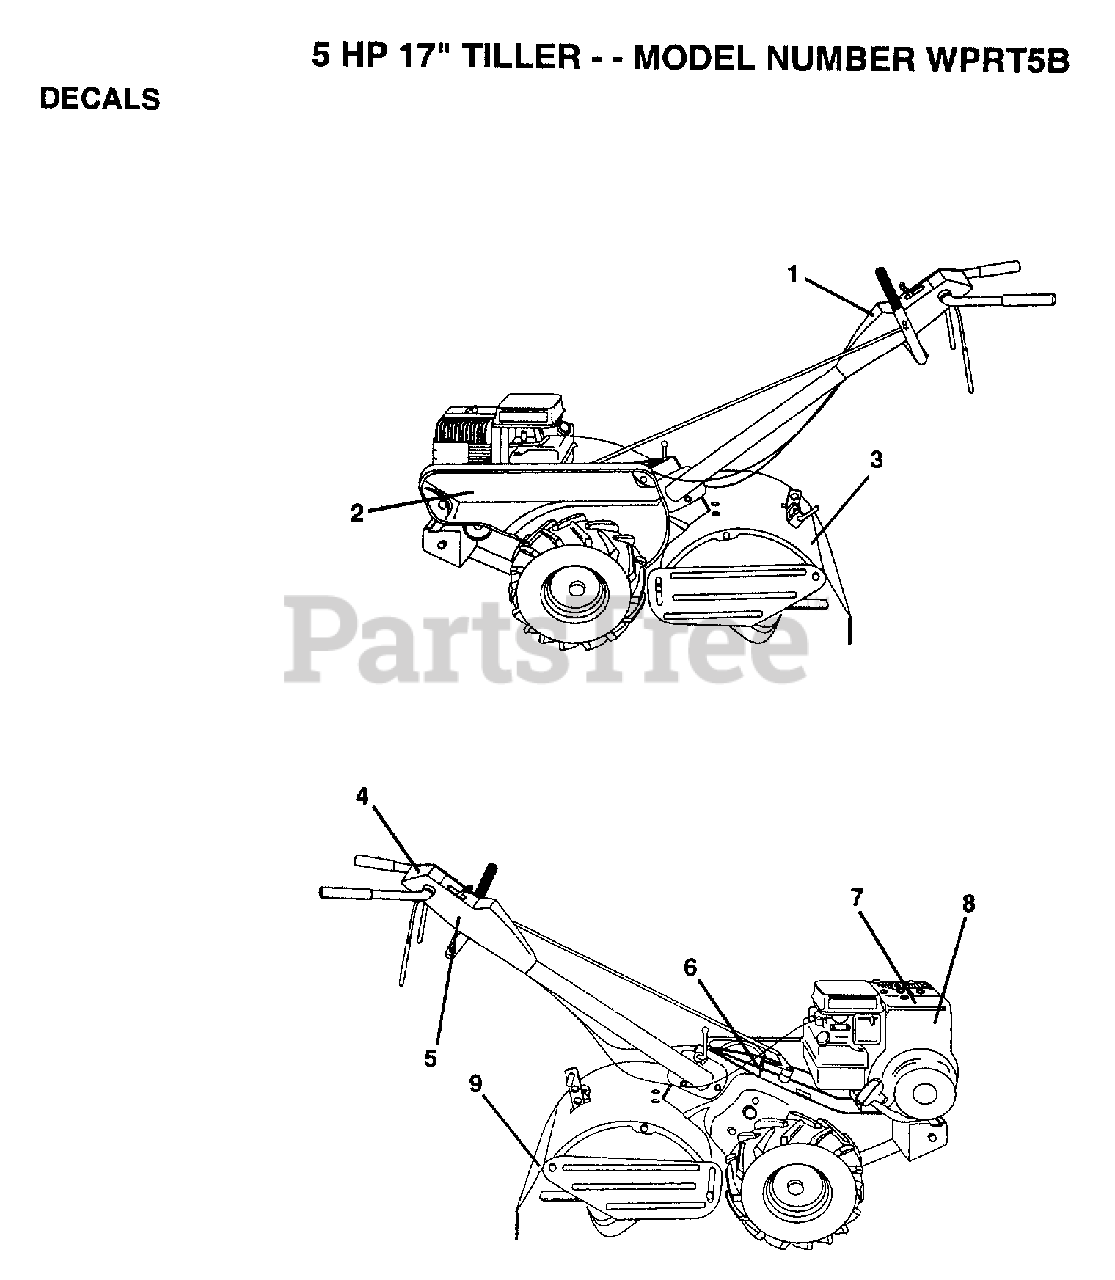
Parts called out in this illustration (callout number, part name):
1	DECAL.PNL.CONTROL
2	DECAL.GD.BELT.5HP
3	DECAL.SHLD.TINE
4	DECAL.INSTRUCTION
5	DECAL TI
6	DECAL CRT
9	DECAL TI
